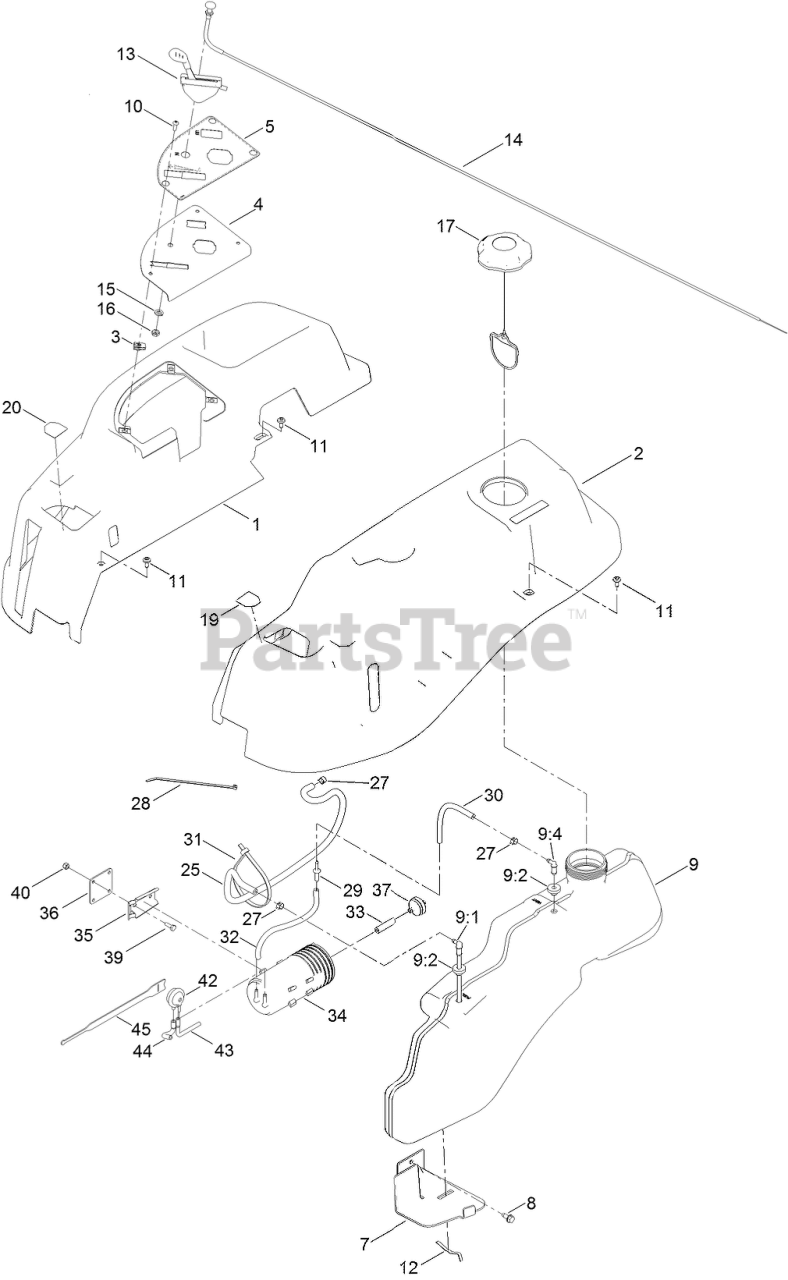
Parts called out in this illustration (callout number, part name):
1	POD-RH
2	POD-LH
4	PLATE-CONTROL
5	DECAL-PANEL, CONTROL
7	SUPPORT-TANK, FRONT
8	SCREW-HWHTF
9	FUEL TANK ASM
9:1	CONNECTOR-ELBOW, 90 DEG
9:2	BUSHING
9:4	FITTING-PLASTIC
10	SCREW-PRH
11	SCREW-SHOULDER
12	SPRING
13	CABLE-THROTTLE
14	CABLE-CHOKE
15	WASHER-LOCK
16	NUT-HJ
17	CAP-FUEL, RATCHETING
19	DECAL-LEVER, CONTROL (LH)
20	DECAL-LEVER, CONTROL (RH)
25	HOSE-FUEL
27	CLAMP-HOSE
28	TIE-CABLE
29	ADAPTOR-ORIFICE
30	HOSE-FUEL
31	TIE-CABLE
32	HOSE-FUEL
33	HOSE-FUEL
34	CANISTER-CARBON, 800CC
35	BRACKET-CANISTER, CARBON
36	PLATE-ADAPTER
37	FILTER-FUEL, INLINE
39	SCREW-HH
40	NUT-LOCK, NI
42	VALVE-CONTROL, VACUUM
43	HOSE-VENT, FORMED
44	HOSE-VENT, FORMED
45	STRAP-VELCRO, CABLE TIE
